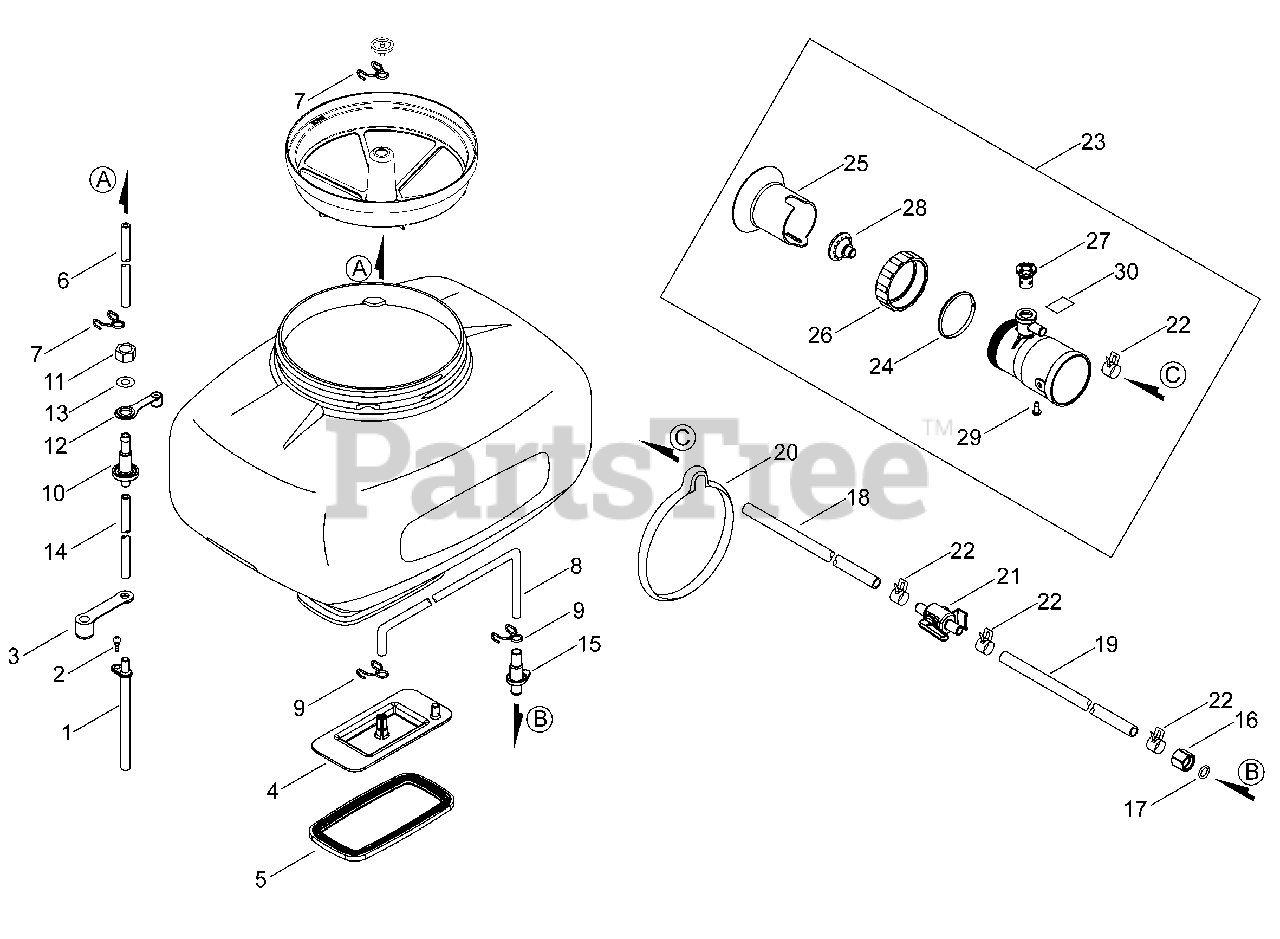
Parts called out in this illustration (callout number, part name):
1	PIPE, VENT
2	SCREW 5×16 SUS
4	PLATE, BOTTOM
5	GASKET, PLATE
6	PIPE, INNER PRESSURE 7×11×500BL
8	PIPE, DISCHARGE 9×13×350
10	CONNECTOR, PIPE
13	WASHER 12
14	PIPE, OUTER PRESSURE 7×11×170L
15	CONNECTOR, PIPE
17	O-RING 3×13
19	PIPE, DISCHARGE 9×13×720L
20	CLIP, TUBE 55
21	VALVE
23	NOZZLE ASSY, MISTING
24	RING, NOZZLE
25	COLLAR, NOZZLE
27	DIAL, METERING
28	NOZZLE ASSY
29	SCREW 5×12
30	LABEL, MIST
